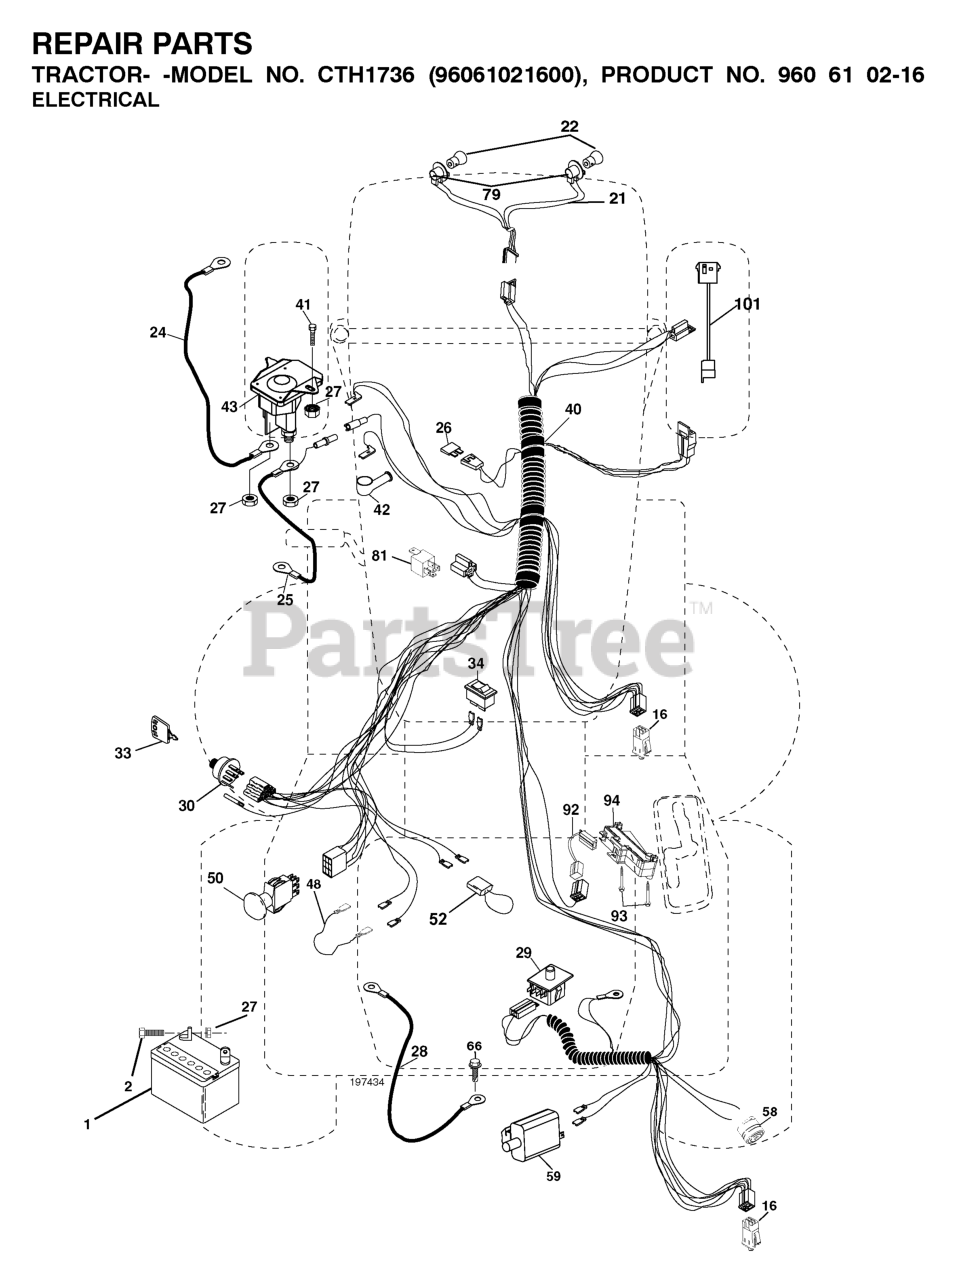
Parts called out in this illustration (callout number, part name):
1	BATTERY 12V .35 AMP
2	BOLT.HEX.1/4.X.3/4.DICHROMATE
16	SWITCH INTERLOOK PUSH-IN
21	HARNESS.LIGHT W/4152J BULBS
24	CABLE.BATTERY.6GA.16"RED
25	CABLE BATTERY
26	FUSE 20AMP
27	NUT
28	CABLE GROUND
29	SWITCH.SEAT.DP W/RAMPS
30	SWITCH.IGN.DELTA.W.LGH.ROS
33	KEY MLD GEN DELTA
40	RP HARNESS.IGN.ELECT.REG.CRD
41	BOLT
42	TERMINAL COVER
43	SOLENOID.W/BRASS.PLUNGER
48	ADAPTER.AMMETER
50	RP.PTO.SWITCH.8 TERMINAL.BLACK
52	WIRE PROTECTION LOOP
58	BUZZER
59	.WITCH.FULL BAGGER.INDICATOR
79	BULB HOLDER ASM.
81	RELAY.ASSY.T
92	HARNESS.PIGTAIL.CONSLE
93	SCREW.PLASTITE
94	MODULE.REVERSE.ROS
101	PIGTAIL.MATNLK.NEW.HAR
